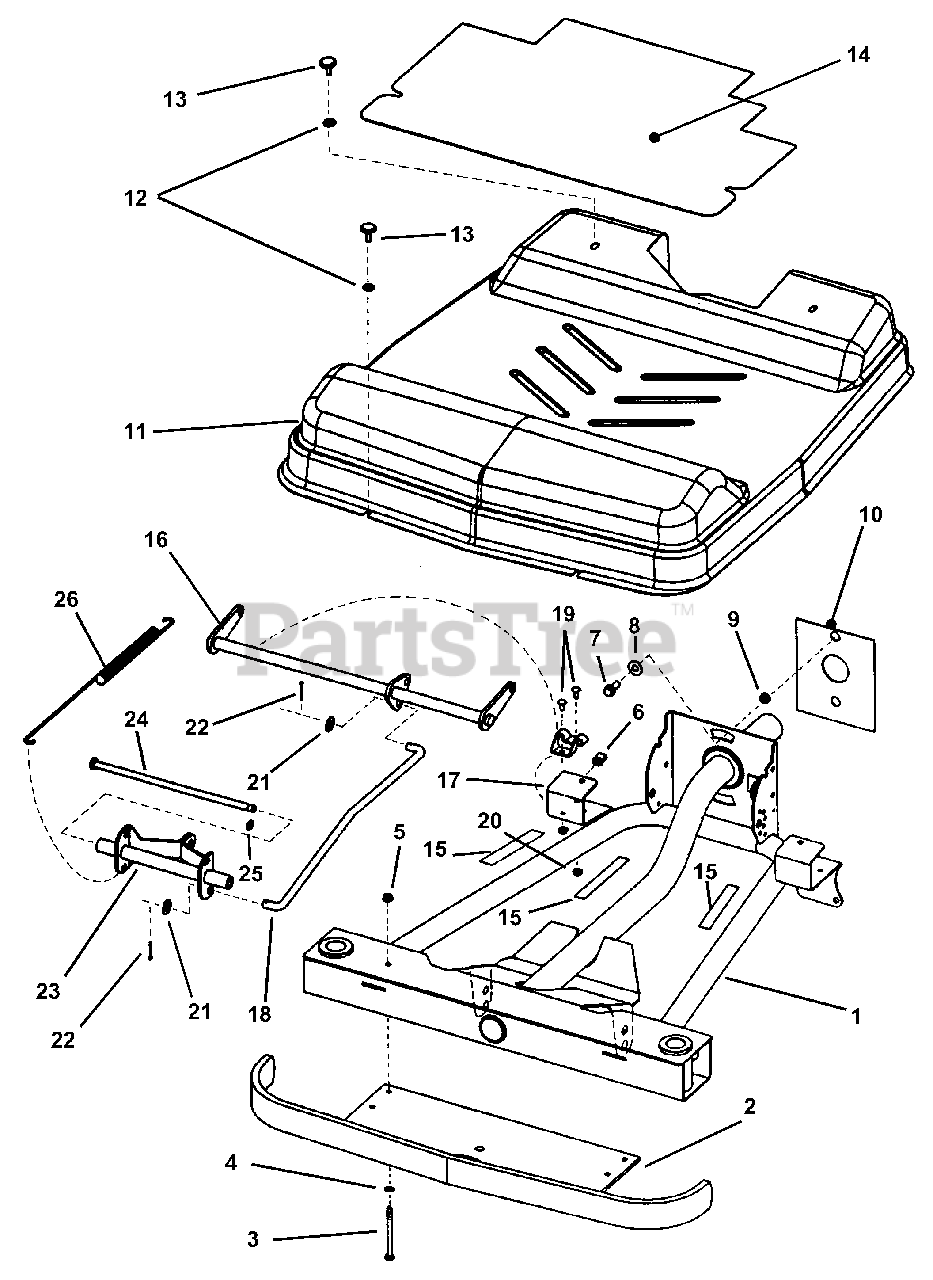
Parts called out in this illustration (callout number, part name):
1	FRAME, Front
2	BUMPER, Front
3	BOLT, 5/16-18 x 3-3/4"
4	WASHER, 5/16" Split Lock
5	NUT, 5/16-18 Hex Flange Lock, Grade 5
6	FASTENER, "U" Type 1/4"-20
7	SCREW, 3/8-16 x 1" Hex Washer Face, Self-Tap
8	WASHER, 3/8" Flat
9	SPACER, Front Frame Pivot
10	PLATE, Front Frame Pivot
11	FLOOR, Front Frame
12	WASHER, 1/4" Internal/External Lock
14	FLOOR MAT
15	PAD, Floor Pan
16	WELDMENT, Rear Lift
17	BRACKET, Saddle
18	ROD, Timing
19	BOLT, 1/4-20 x 5/8" Short Square Neck Carriage
20	NUT, 1/4-20 Flange Lock
21	WASHER, 1/2" Flat
22	PIN, 1/8 x 1" Cotter
23	WELDMENT, Front Lift
24	ROD, Deck Support
25	RING, .438 External Retaining
26	SPRING, Deck Assist
